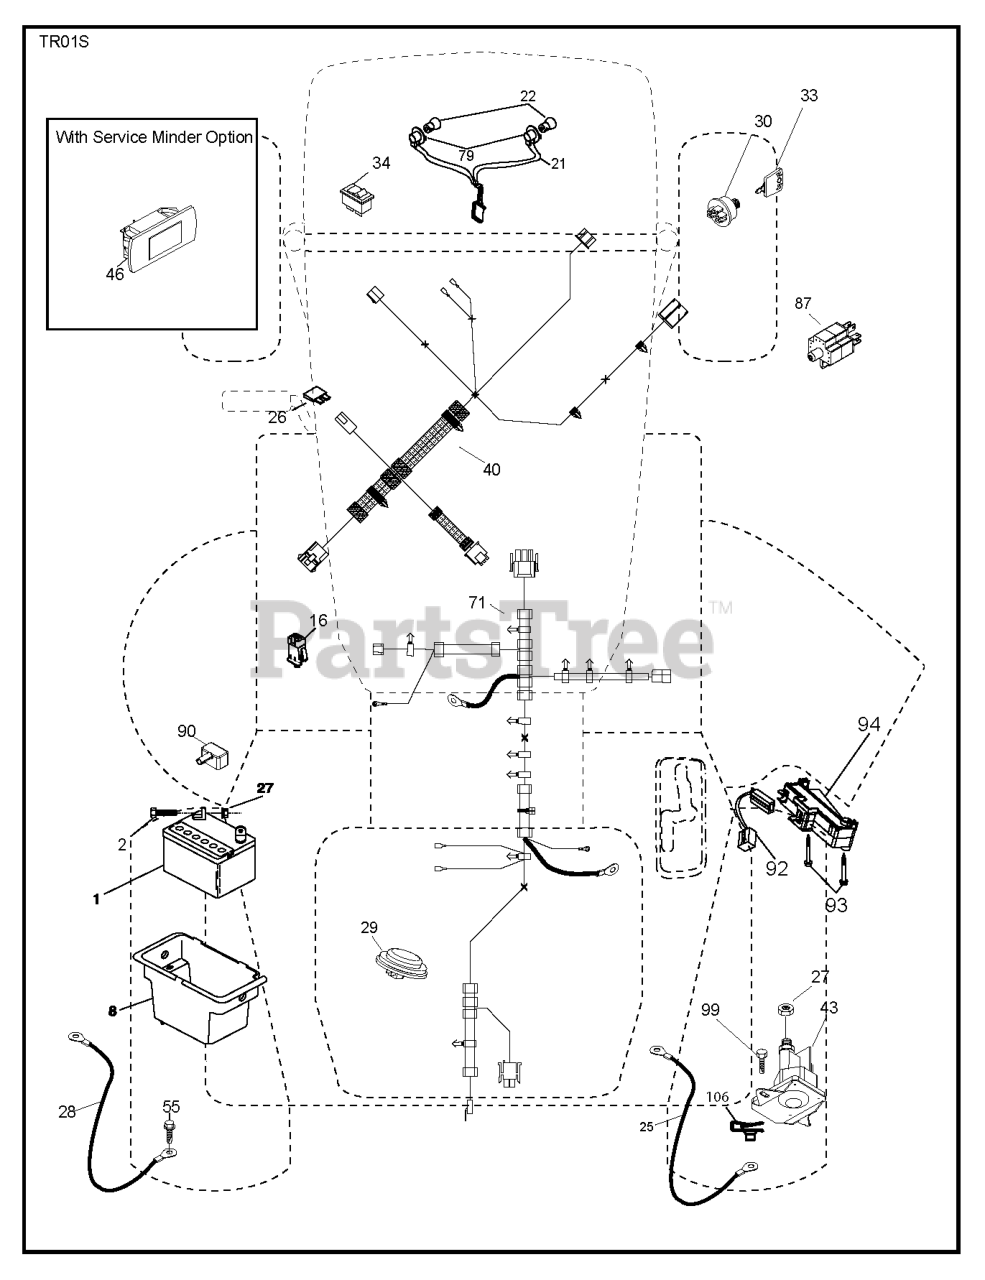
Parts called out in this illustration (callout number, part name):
1	Battery 12 Volt 25 Amp
2	BOLT.HEX.1/4.X.3/4.DICHROMATE
8	BOX.BATTERY.MNT.REAR.L
16	SWITCH INTERLOOK PUSH-IN
21	HARNESS.LIGHT W/4152J BULBS
25	CABLE.BATT.RED.8GA.17
26	FUSE 20AMP
27	NUT
28	CABLE.GROUND.REAR.BATTERY.8G
29	SWITCH.SEAT.DELTA.OPC.
30	SWITCH.IGN.DELTA.W.LGH.ROS
33	KEY.CHAIN.BLISTER.PACK.GEN.USA
40	HARNESS.TEX.DASH.MAN.REAR BATT
43	SOLENOID.W/BRASS.PLUNGER
55	SCREW 5/16"
71	HARNESS.TEX.CHSSIS.REAR.BATT
79	BULB HOLDER ASM.
87	SWITCH.INTRLCK.CLUTCH.
90	COVER.TERMINAL.BATTERY
92	HARNESS.PIGTAIL.CONSLE
93	SCREW.PLASTITE
94	MODULE.REVERSE.ROS
99	SCREW HEXWSHR 1/4-20X3/4
106	1/4-20 U NUT
